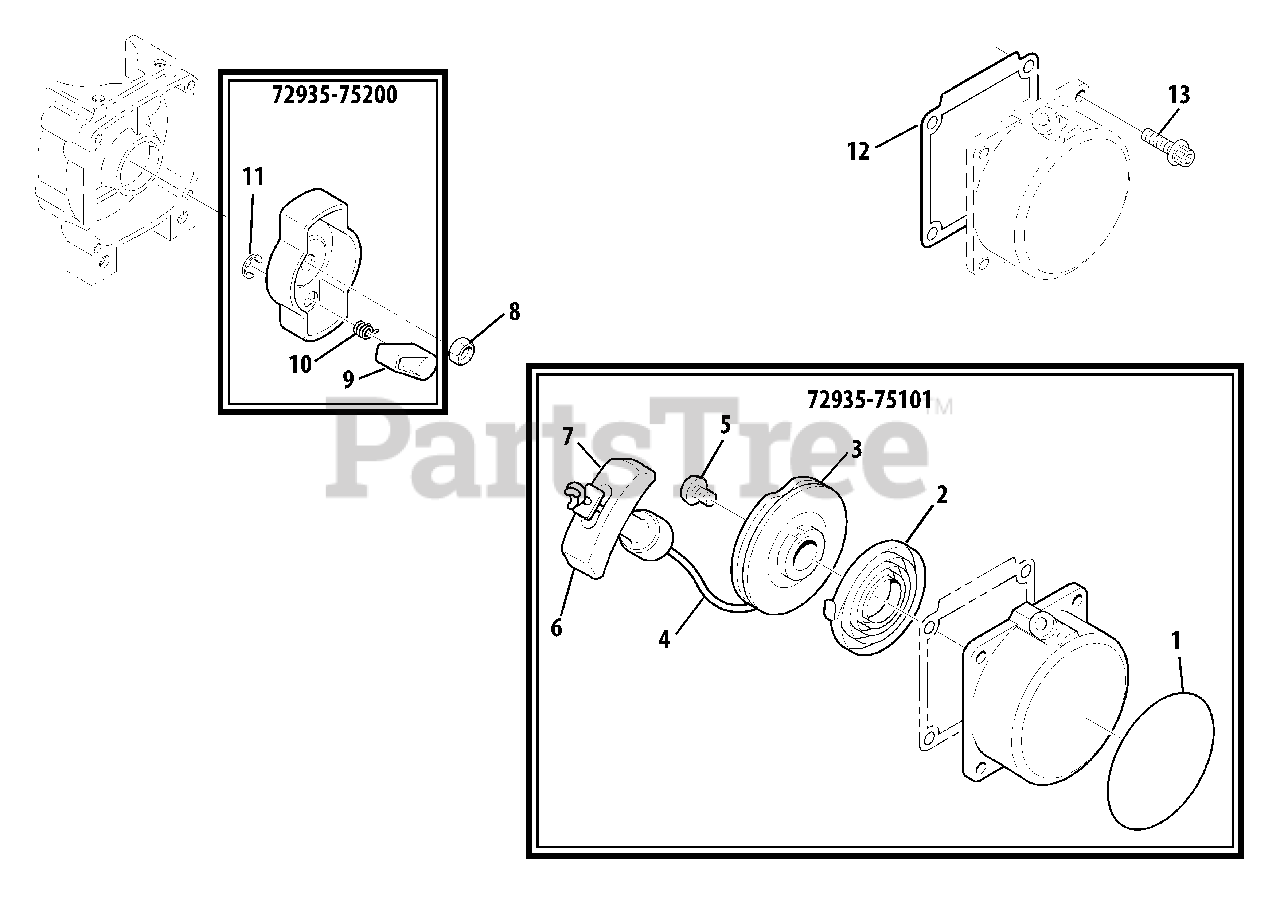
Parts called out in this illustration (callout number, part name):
1	LABEL, SHINDAIWA PROFESSIONAL
2	SPRING, RECOIL
3	REEL, ROPE
4	ROPE, STARTER
5	SCREW 5
6	GRIP, STARTER
7	RETAINER, ROPE
8	NUT 8
9	PAWL, STARTER
10	SPRING, RETURN
11	E-RING 4
12	GASKET, RECOIL STARTER
13	BOLT, ADHESIVE M4×16
72935-75101	STARTER ASSY, RECOIL
72935-75200	PULLEY ASSY, STARTER
